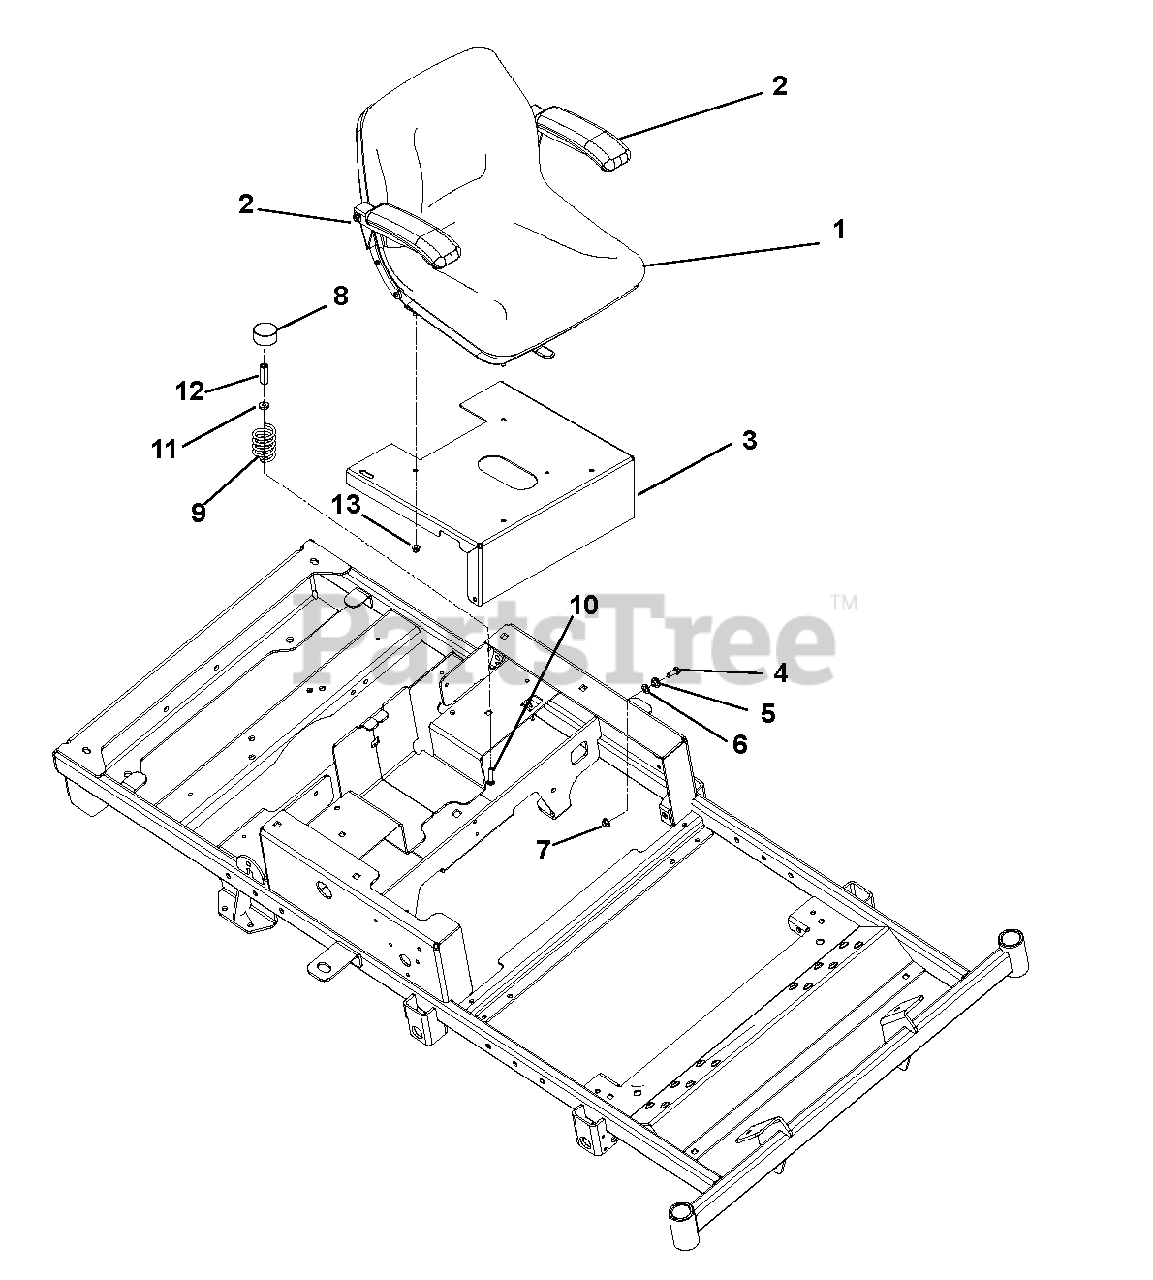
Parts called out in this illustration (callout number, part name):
1	SEAT, MILSCO XB-180
2	KIT, SEAT ARM RESTS
3	SEAT PLATE
4	@BLT-HEX .38-16X1.00 GR5 YWZC
5	BSHG-FLG .385X.500X.875X.406
6	WSHR-FL-STL .52X.827X.062 YWZC
7	@NUT-LK-NYL-FLG .38-16 YWZC
8	HUB CAP
9	SPRING, SEAT
10	@BLT-RDHDSQNK .31-18X1.50 G5YZ
11	WSHR-FL-STL .328X.87X.179 YWZC
12	NUT, COUPLING 5/16-18 X 1 3/4
13	@NUT-LK-NYL-FLG .31-18 YWZC
